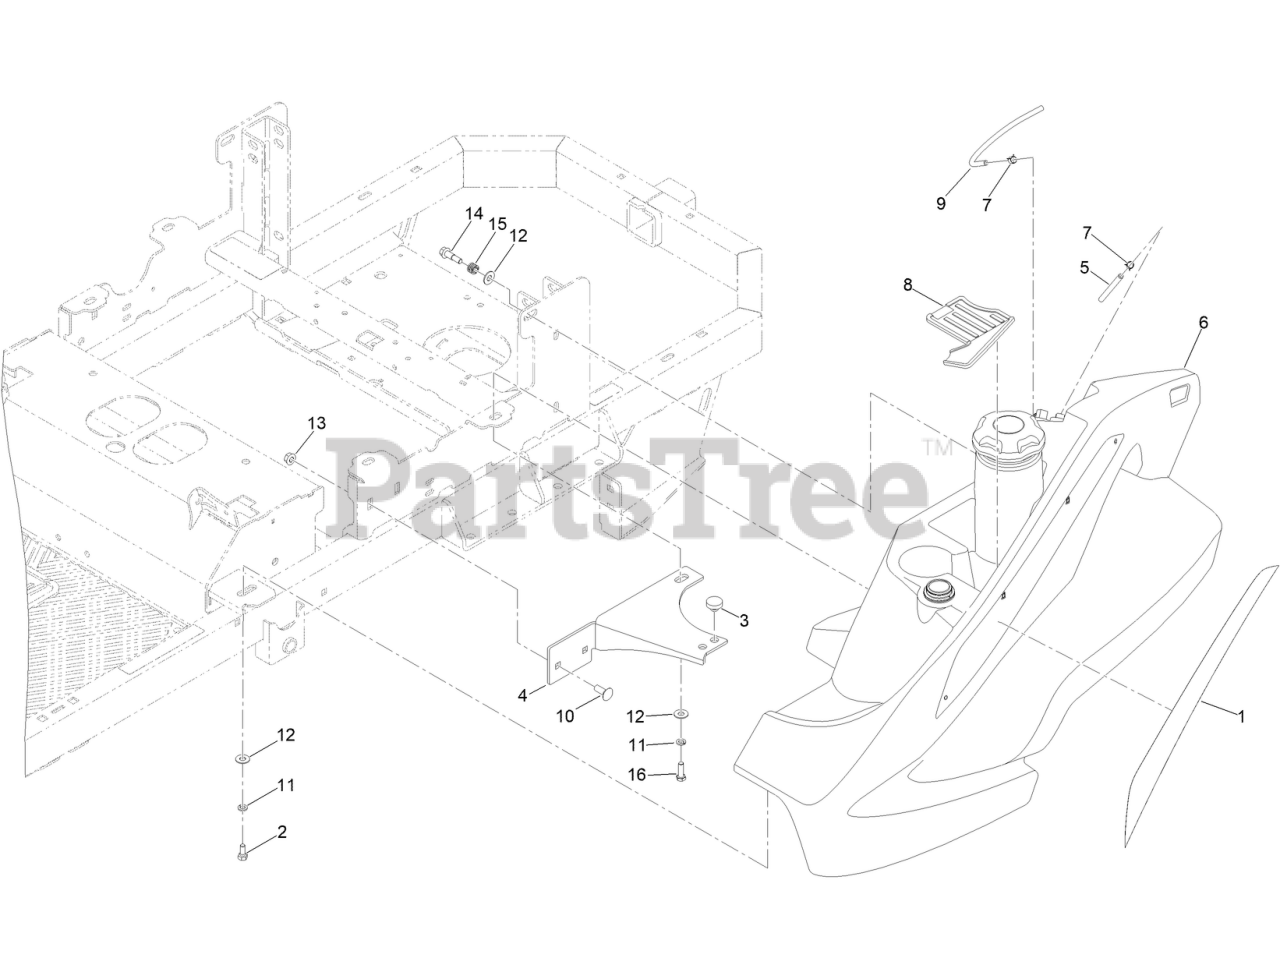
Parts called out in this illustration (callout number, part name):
1	DECAL-POD LH
2	SCREW-HH
3	PUSH-IN RUBBER BUMPER MWR FLOOR
4	BRACKET-TANK SUPPORT
5	MWR FUEL TANK BLACK 3/16IN VENT TUBE 1FT
6	MWR GASOLINE FUEL TANK ASSY
7	1/2IN (#8) HOSE CLAMP
8	RUBBER TANK STORAGE COMPARTMENT INSERT
9	1/4IN SAE J30R7 BULK HOSE 1FT
10	3/8-16 X 1 CARRIAGE BOLT YZ GR.8
11	WASHER-LOCK
12	WASHER-FLAT
13	3/8-16 HEX FLANGE NUT W/SERR ZINC YELLOW
14	SCREW-SHOULDER,HHF
15	SPRING-COMPRESSION
16	SCREW-HH
